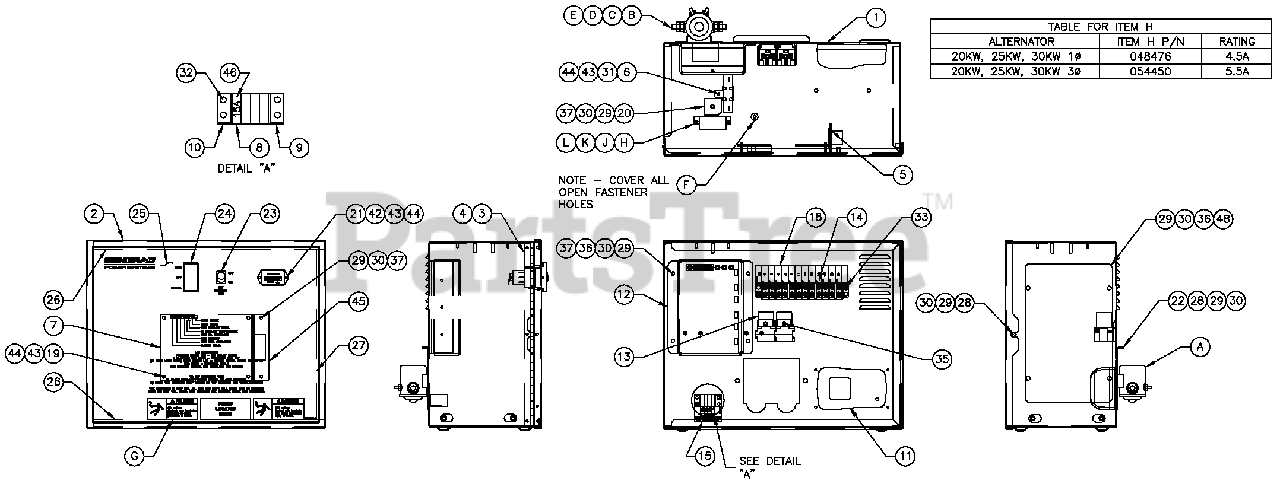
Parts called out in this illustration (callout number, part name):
1	ENCL HSB CONTROL PANEL
2	COVER CONTROL PNL W/HOUR METER
3	HINGE CONTINUOUS H-PANEL
4	RIVET POP .125 X .275 SS
5	SCREW PPPH HI-LO #4-24 X 3/8
6	WASHER FLAT M3
7	ASSY PCB R-200A CNTRL 3600
8	HOLDER FUSE WICKMANN 178.6150
9	ADPTR RH SIDE WICKMAN 178.6191
10	ADPTR LH SIDE WICKMAN 178.6192
11	BATC 13.4VDC 2.5A W/8POS PLUG
12	ASSY VOLTAGE REGULATOR 60HZ
13	RELAY 12VDC C FORM W/DIODE
14	BLOCK TERM 20A 12 X 6 X 1100V
15	DECAL CPL CONTROL PANEL FUSES
18	DECAL CPL 3.9L TB1
19	SPACER 9.5H 3.2 ID
20	DIO BRIDGE 25A 600V
21	HOUR METER 10-80VDC
22	PLATE HARNESS CLAMP
23	SWITCH RKR DPST 125V SPD
24	SWITCH RKR DPDT ON-OFF-ON
25	DECAL CONTROL PNL W/HOUR METER
26	SEAL COVER 3.18 X 12.7 X 382
27	SEAL COVER 3.18 X 12.7 X 283
28	SCREW HHPM M5-0.8 X 12
29	WASHER FLAT M5
30	WASHER LOCK M5
31	RES WW 15R 5% 25W QK CONN
32	SCREW PHTT M3.5-0.6 X 10
33	SCREW PHTT M3.5-0.6 X 16
35	SCREW PHTT M4-0.7 X 10 ZYC
36	SCREW PPHM M5-0.8 X 12 ZNC
37	NUT HEX M5-0.8 G8 CLEAR ZINC
42	SCREW PHM M3-0.5 X 10 BLACK
43	WASHER LOCK M3
44	NUT HEX M3-0.5 G8 YEL CHR
45	SUPPORT ANGLE PCB
46	FUSE ATO TYPE 15 AMP (BLUE)
48	PLATE COVER H PANEL
A	RELAY SOLENOID 12VDC PNL MNT
B	SCREW HHC 1/4-20 X 3/4 G5
C	WASHER FLAT 1/4-M6 ZINC
D	WASHER LOCK M6-1/4
E	NUT HEX 1/4-20 STEEL
F	SEAL WEATHER .45"DIA
G	DANGER HIGH VOLTAGE (SPANISH)
H	CIRCUIT BREAKER
J	WASHER FLAT M3
K	WASHER LOCK M3
L	NUT HEX M3-0.5 G8 YEL CHR
